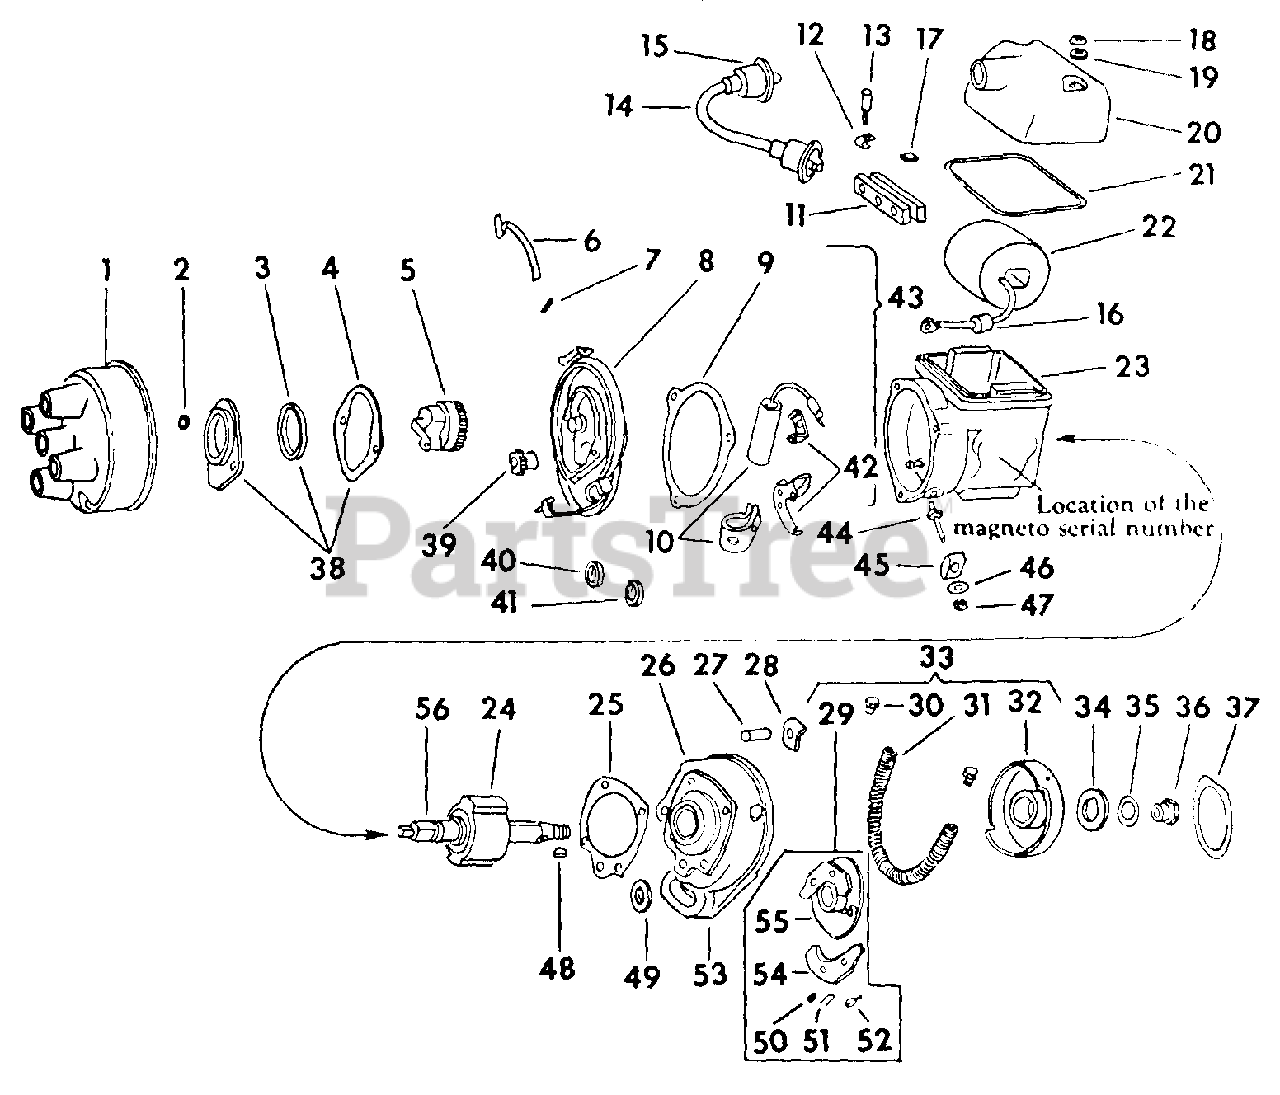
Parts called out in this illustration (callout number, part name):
1	CAP, DISTRIBUTOR
2	WASHER, DISTRIBUTOR GEAR COVER
3	FELT, DISTRIBUTOR GEAR COVER
4	GASKET, DISTRIBUTOR GEAR COVER
5	ROTOR, DISTRIBUTOR
6	SPRING, DISTRIBUTOR CAP
7	PIN, DISTRIBUTOR CAP SPRING
8	BODY ASSEMBLY, DISTRIBUTOR
9	GASKET, DISTRIBUTOR BODY
10	CONDENSER, W/CLAMP
10	CONDENSER ASSEMBLY
12	CLIP, COIL CORE
13	SCREW, COIL CORE HOLD-DOWN
14	CABLE-W/TWO NIPPLES, COIL TO DISTRIBUTOR
15	NIPPLE, COIL TO DISTRIBUTOR CAP
16	TUBE, PRIMARY LEADOUT SEALING
18	WASHER, COIL COVER SCREW
19	WASHER, COIL COVER SEAL
21	GASKET, COIL COVER
22	COIL,
23	FRAME-W/CUP, MAGNETO
24	ROTOR, ASSEMBLY
25	GASKET, MOUNTING FLANGE
26	FLANGE ASSEMBLY, MOUNTING
27	PIN, IMPULSE COUPLING STOP
28	CLIP, MAGNETO MOUNTING
29	MEMBER ASSEMBLY, MAGNETO
30	BUTTON, SPRING END
31	SPRING, MAGNETO COUPLING
32	MEMBER, DRIVE
33	ROTATING UNIT ASSEMBLY, IMPULSE COUPLING
34	WASHER, MAGNETO MEMBER LOCK
35	WASHER, 1/2 IMPULSE COUPLING LOCK
36	NUT, IMPULSE COUPLING
37	GASKET, MAGNETO
38	COVER
39	PINION, ROTOR
40	RETAINER, DISTRIBUTOR BODY FELT
41	FELT, DISTRIBUTOR BODY
42	POINT SET, MAGNETO
43	SET, POINTS AND CONDENSER
44	SCREW, W/INSULATOR TERMINAL
44	SCREW, TERMINAL
45	INSULATOR, SPRING ANCHOR TERMINAL
46	WASHER, TERMINAL INSULATOR
47	WASHER, STATIONARY POINT SUPPORT
48	KEY, NO. 3 WOODRUFF TERMINAL
49	WASHER, MAGNETO BOLT
50	WASHER, PAWL FIN
51	RING, PAWL PIN SNAP
52	SPRING, PAWL
53	OILER, BEARING
55	MEMBER, MAGNETO
56	CAM, BREAKER
